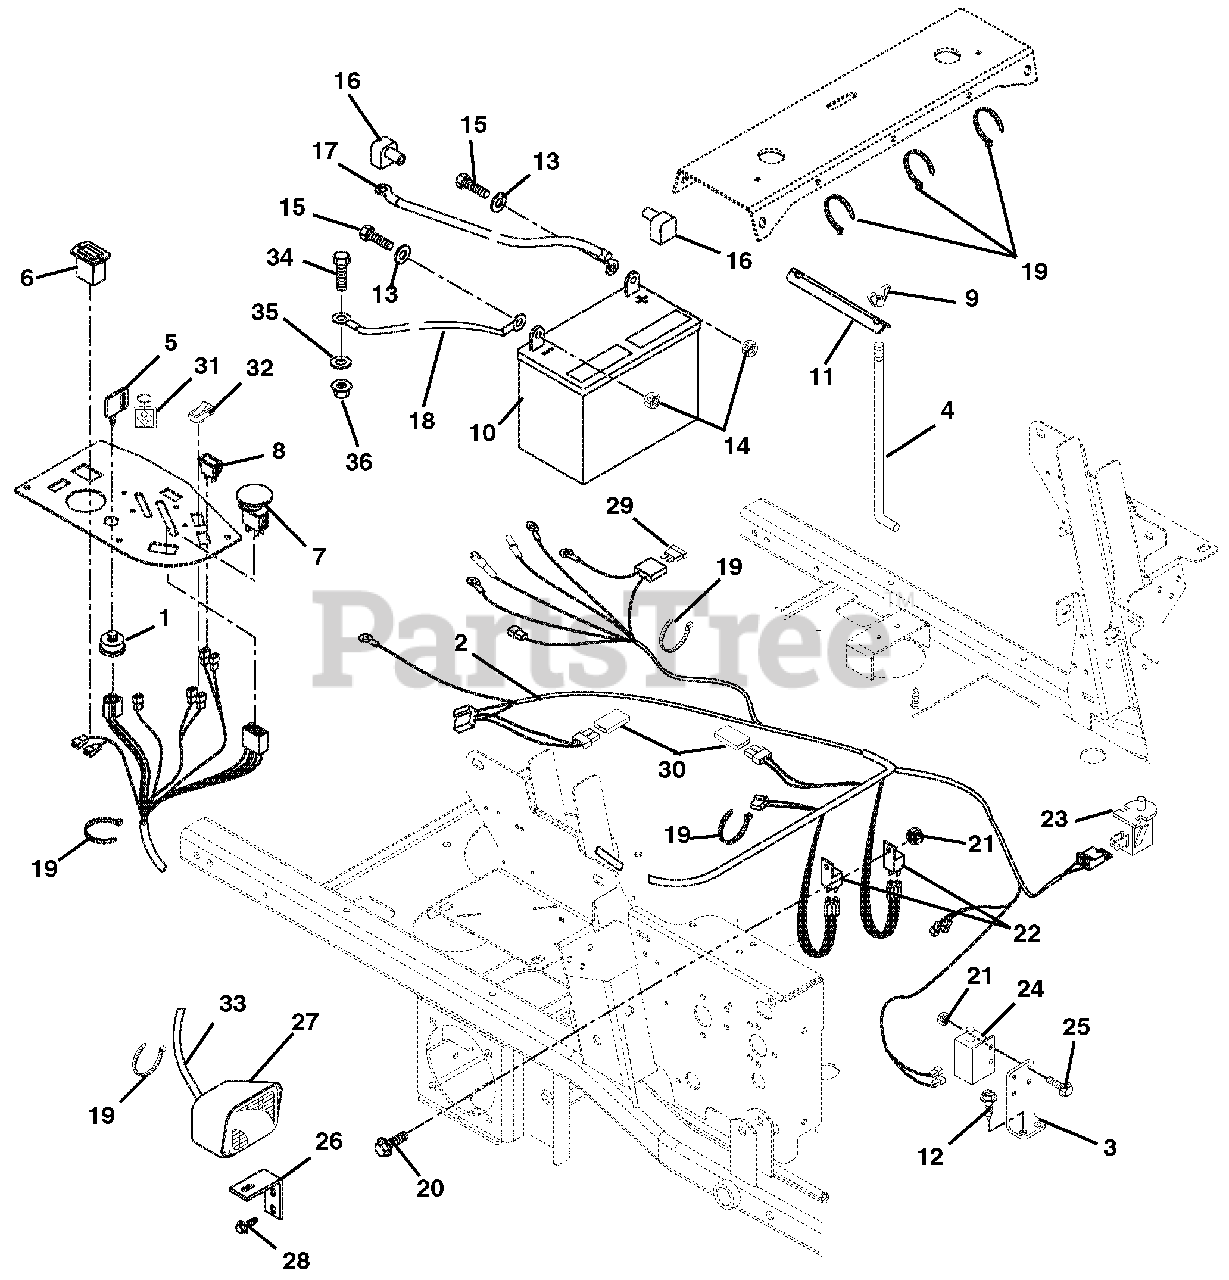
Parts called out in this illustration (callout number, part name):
1	Switch, Ignition
2	Harness, Z 6-Pin Wiring (045, 046, 047, 049, 052, 053)
3	Mount, Safety Switch
4	Rod, Battery Holddown .25 x 6.62
5	Key, with Shield
6	Hour Meter
7	Switch, PTO Clutch
8	Light-Indicator Kit (045, 046, 047, 049, 052, 053)
9	Nut-Locking Wing .25-20
11	Hold Down
12	Screw-Tapping .25-20 x .50 Hex Washer Head
13	Washer-Flat-Steel .281 x .620 x .065
14	Nut-Locking-Top-Flange .25-20
15	Bolt-Hex .25-20 x .75 Grade 5
16	Battery Terminal Boot, Red
17	Starter Cable 13 in.
18	Ground Cable
19	Cable Tie
20	Screw-Machine 10-24 x .50 Hex Washer Head
21	Nut-Locking-Nylon 10-24 With Insert
22	Relay (Included with Harness)
23	Switch- Snap Mounting
24	Switch-Single Pole
25	Screw-Machine 10-24 x .75 Hex Washer Head
26	Bracket, Headlight Mounting Left
27	Headlight
28	Screw-Tapping .38-16 x .50 Hex Washer Head
29	Fuse, 30 Amp (Included with Harness)
30	Diode, Connector Shell
31	Key Chain
32	Switch, Light
33	Harness, Headlight Kit
34	Bolt-Hex .31-18 x .75 Grade 5
35	Washer-Flat-Steel .344 x .688 x .065
36	Nut-Locking-Top-Flange .31-18
